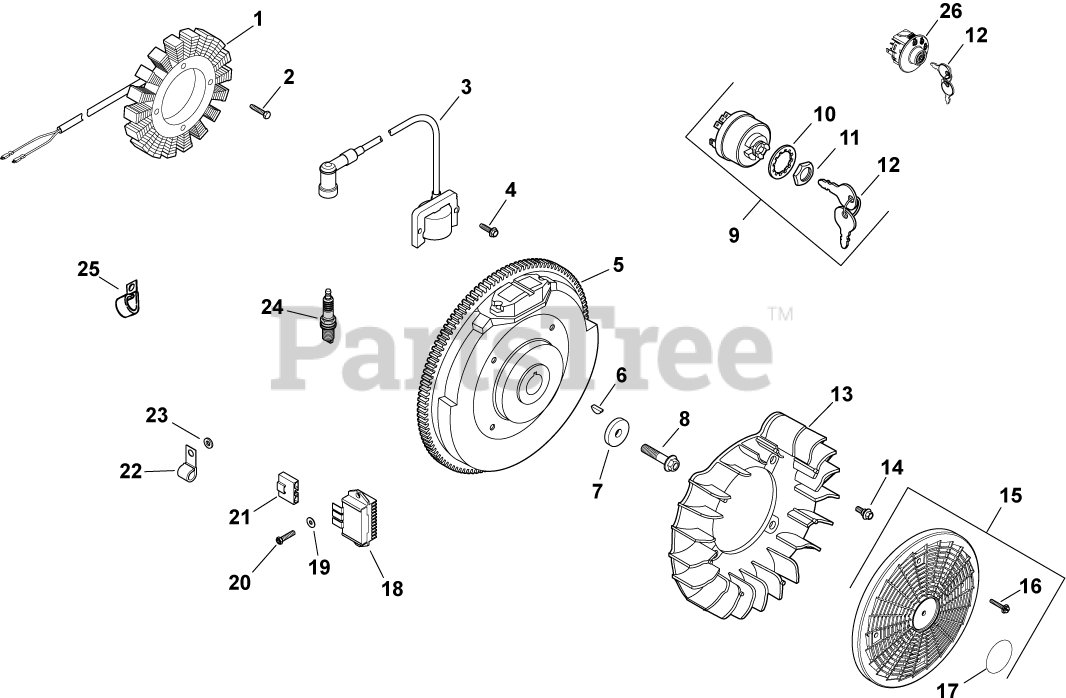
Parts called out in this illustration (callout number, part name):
1	KIT, 15 / 20 AMP STATOR
2	SCREW, M5X0.8X25 - (#25086402S)
3	KIT, MODULE IGNTN (CDI FIXED)
4	SCREW, FLG THD FRM M5X.8X20-(#25086399S)
5	FLYWHEEL, PAINTED-USE 24 025 59-S
6	KEY, 3/16" X 5/8"
7	WASHER, FLAT 13/32"
8	SCREW, FLG M10X1.5X45 - (#25086361S)
9	SWITCH ASSY, KEY (KM)-USE 25 099 32-S
10	WASHER, INTERNAL TOOTH
11	NUT, KEY SWITCH
12	KEY, SET -USE 48 340 01-S
13	FAN USE 24 755 253-S
14	BOLT, SHOULDER
15	KIT, GRASS SCREEN
16	SCREW, FLG SEMS M4X.7X25
17	DECAL, GRASS SCREEN USE 24 113 499-S
19	WASHER, FLAT 7/32"
20	SCREW, PHL HD #11-16X7/8"
21	CONNECTOR, BODY (KM)-USE 25 155 41-S
22	CLIP, CABLE
23	WASHER, FLAT 1/4" (O.D. 1/2")
24	PLUG, SPARK (PRO SERIES)
25	CLIP, CABLE - USE 24 154 10-S
26	KIT, KEY SWITCH (SNAP-IN)
